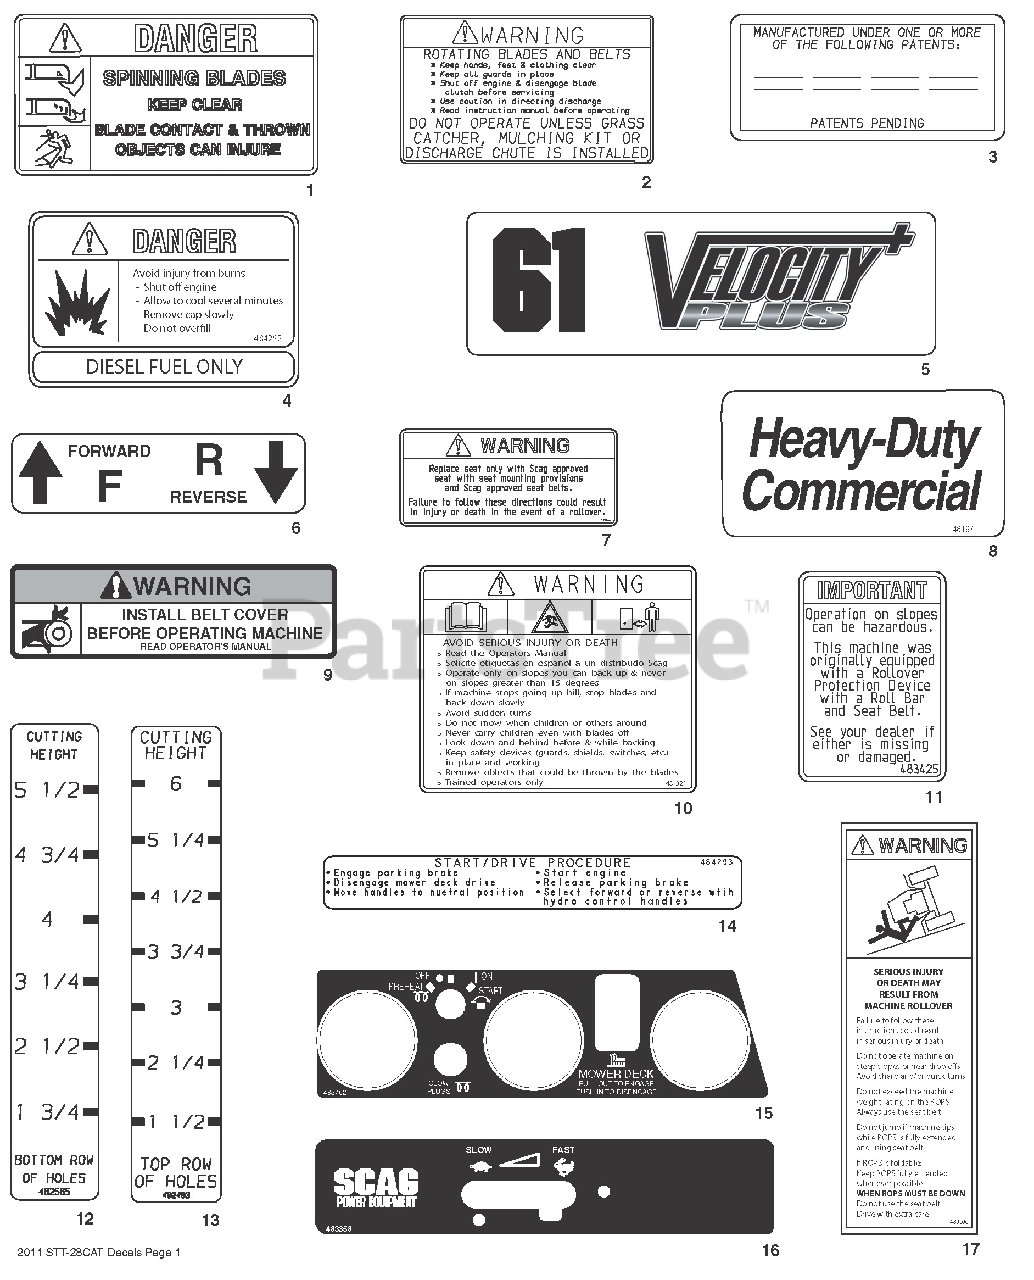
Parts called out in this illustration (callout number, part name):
1	Decal, Danger-Spinning Blades
2	Decal, Warning-Rotating Blades
3	Decal, Patents
4	Decal, Fuel Tank
5	Decal
6	Decal, Traction Control
7	Decal, Seat Replacement
8	Decal, Heavy Duty Commercial
9	Decal, Belt Cover
10	Decal, Warning
11	Decal, ROPS
12	Decal, Cutting Height - Lower
13	Decal, Cutting Height - Upper
14	Decal, Start/Drive Procedure
15	Decal, Instrument Panel - Upper
16	Decal, Instrument Panel - Lower
17	Decal, ROPS Warning
